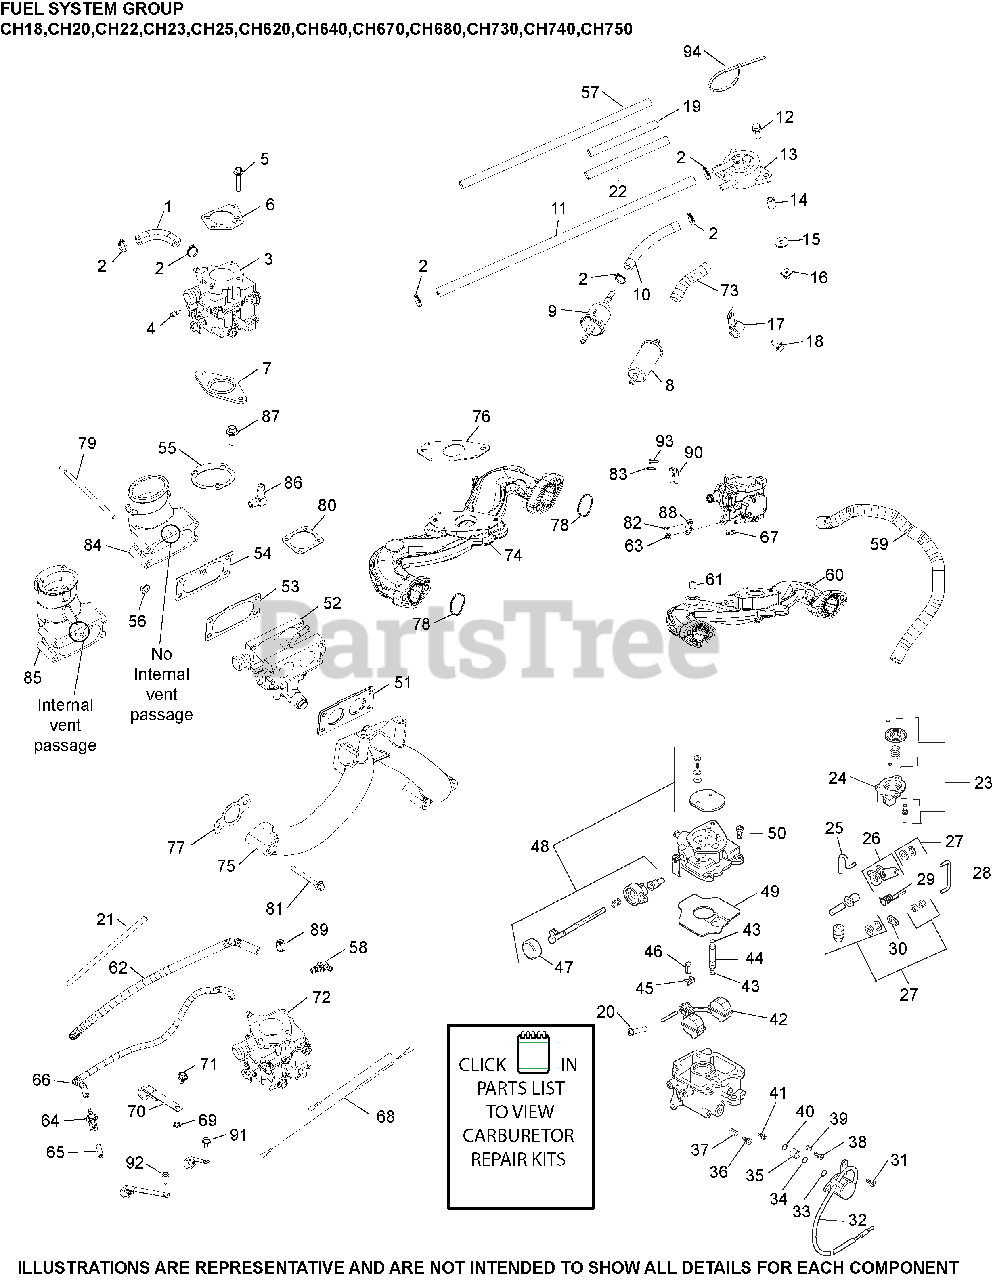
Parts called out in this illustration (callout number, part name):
1	HOSE,LW PERM.FUEL 24.00"-USE 25 111 81-S
2	CLAMP, HOSE (KM)-USE 25 237 31-S
3	KIT, CARBURETOR W/GASKETS
5	SCREW, FLG M6X1.0X25
9	FILTER, FUEL
32	KIT, SOLENOID
42	KIT, REPAIR FLOAT
48	KIT, REPAIR CHOKE
64	CONNECTOR, EVAPORATIVE
65	CAP, MASKING
66	HOSE, EVAPORATIVE 20"
68	LEAD, GROUND
69	WASHER, INT TOOTH LOCK 1/4"
74	KIT, INTAKE MANIFOLD
76	WASHER, INT TOOTH LOCK 1/4"
78	O-RING, INTAKE PORT
